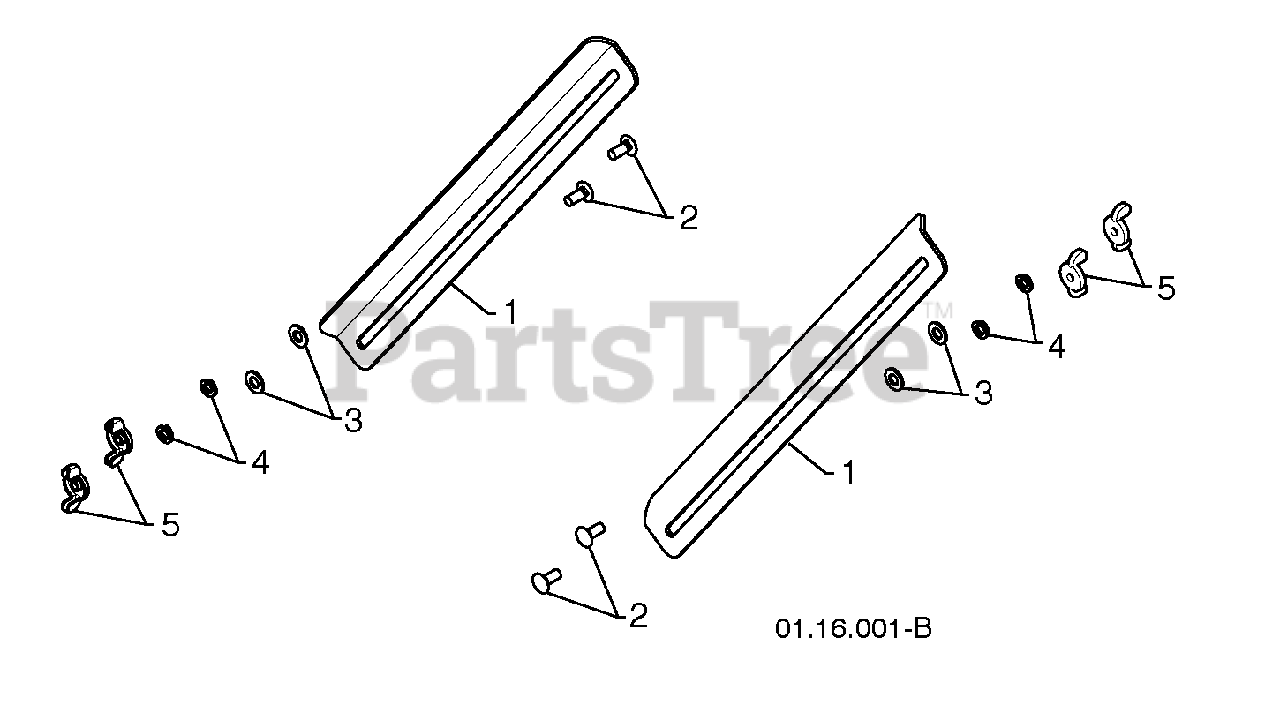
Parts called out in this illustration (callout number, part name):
1	DRIFT CUTTER BAR
2	CARRIAGE BOLT 5/16-18 X .750
3	PLASTIC WASHER
4	LOCKWASHER 5/16
5	NUT 5/16-18
